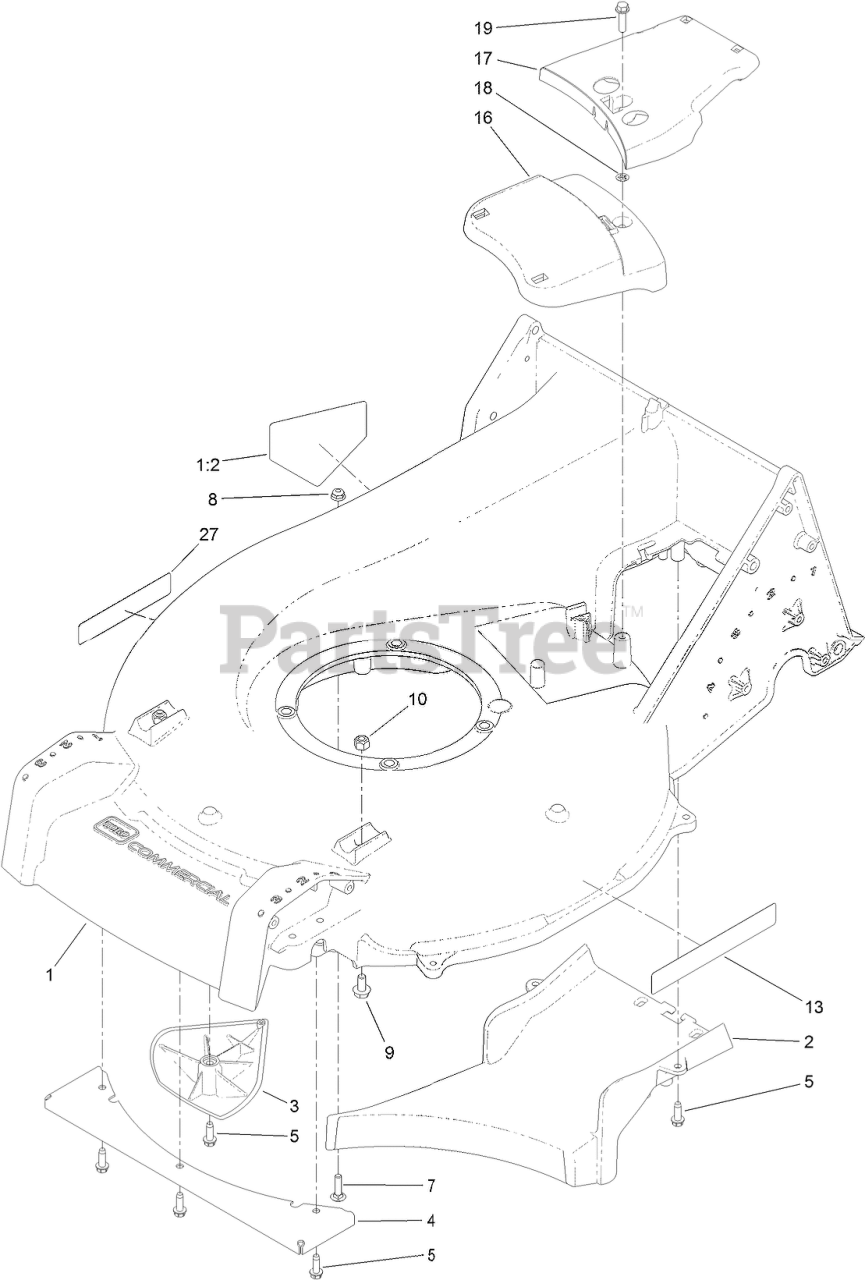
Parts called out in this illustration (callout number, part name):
1	HOUSING ASM
1:2	DECAL-DANGER
2	FLOOR-CHUTE
3	KICKER
4	GUARD-TOE, FRONT
5	SCREW-HWHTF
7	SCREW-CARR
8	NUT-HF
9	SCREW-HHF
10	NUT-LOCK, NI
13	DECAL-RECYCLER
16	COVER-BELT, FRONT
17	COVER-BELT, REAR
18	NUT-RETAINER
19	SCREW-HWHTF
